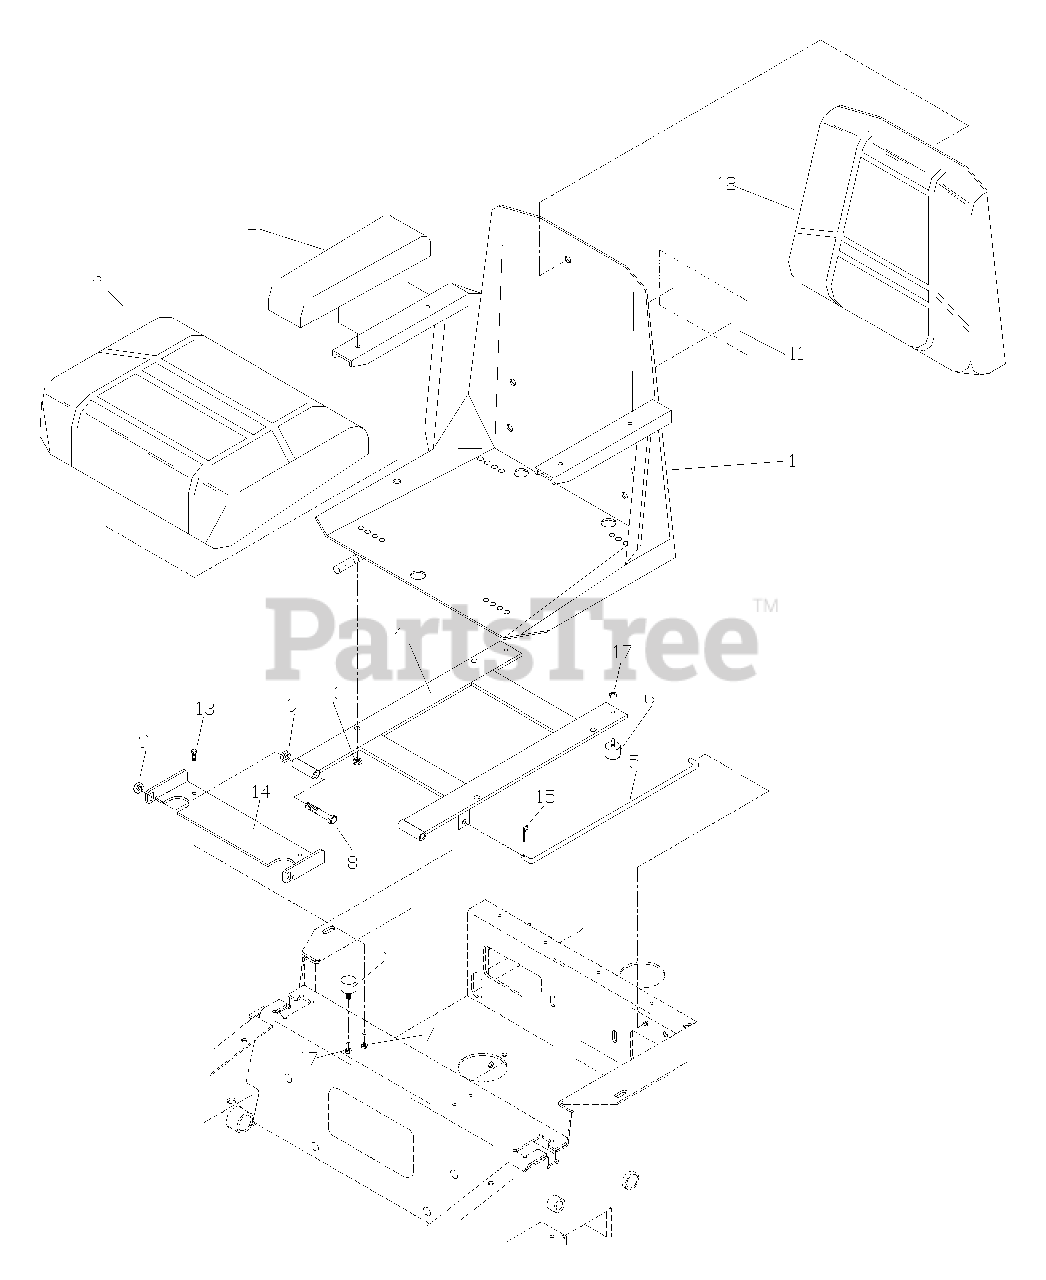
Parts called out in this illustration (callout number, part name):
1	SEAT COMPLETE
2	ARM REST CUSHIONS
3	SEAT CUSHION
4	SEAT MOUNT
7	NUT 1/4 LOCK
8	HCS 3/8 X 3.0
9	NUT 3/8 LOCK
10	NUT 5/16 LOCK
11	DECAL, CROWN
12	BACK CUSHION
13	HCS 1/4 X 3/4
14	SEAT BRACKET W/DECAL
15	COTTER PIN
16	SEAT RAILS
17	NUT 1/4 NYLOC
18	SEAT HARNESS
19	SEAT SWITCH
